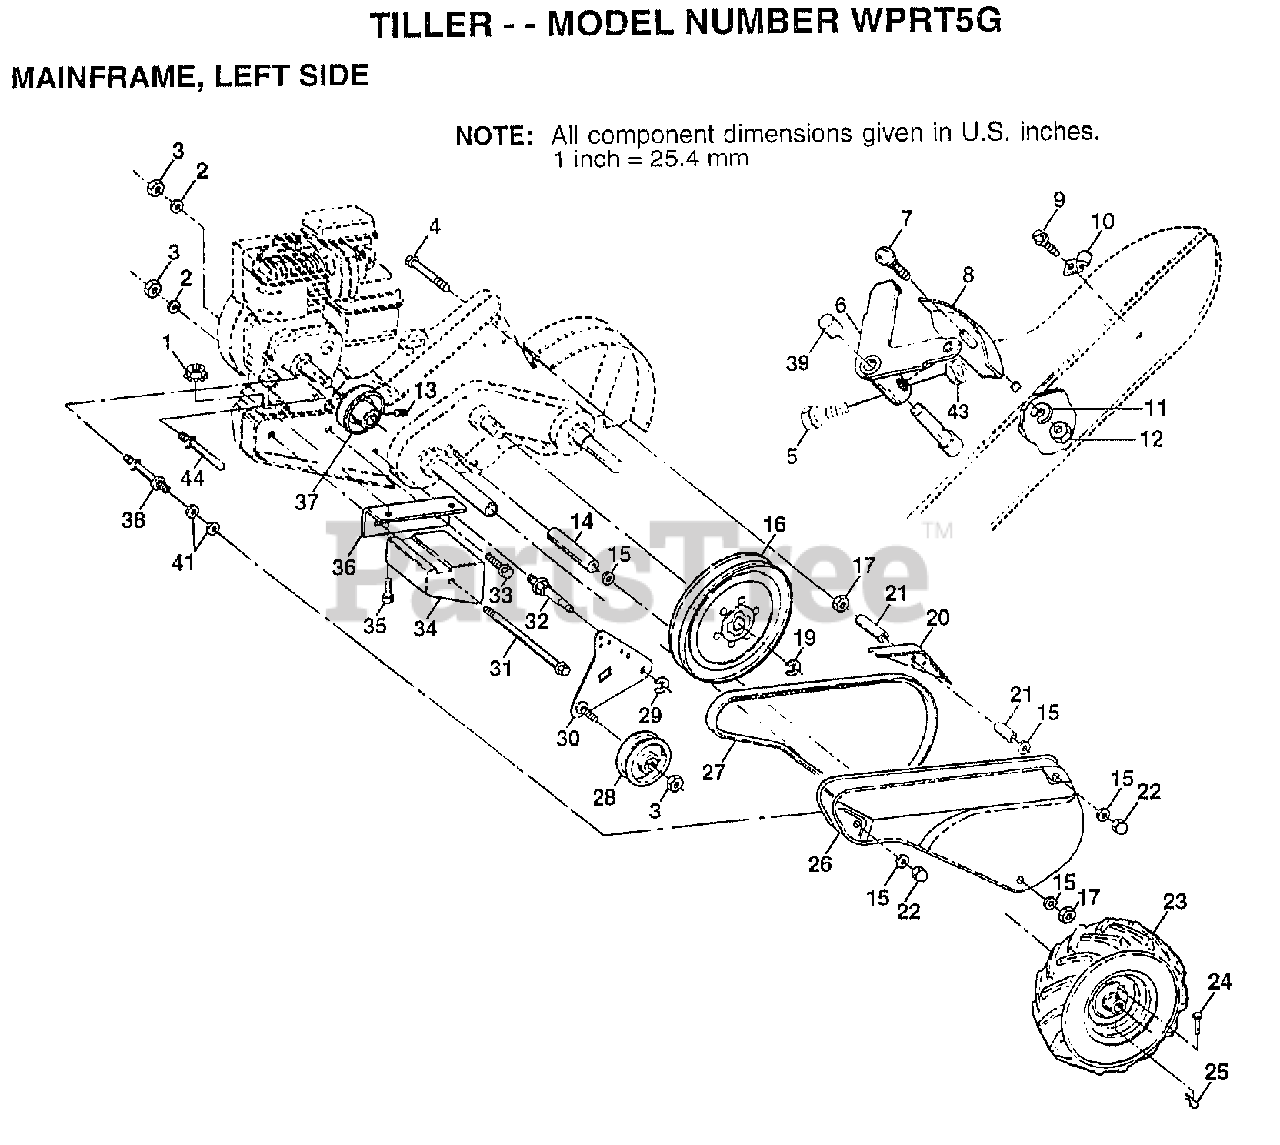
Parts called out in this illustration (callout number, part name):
2	LOCKWASHER
3	NUT.HEX.3/8-16UNC
4	BOLT TI
5	"SCREW-LEVER,SHI"
6	LEVER ASM CRT
7	BOLT
8	PANEL TI
10	CONDIUT CLIP T
11	LOCKWASHER
13	SET SCREW
14	SPACER
15	WASHER
16	SHEAVE.TRANS.
17	NUT.HEX.5/16-18
20	GUARD CRT
21	SPACER.SPLIT
22	NUT TI
23	TIRE TI
24	RIVET.DRILL.1.75
27	BELT-V
28	PULLEY-IDLER TI
29	KLIP RING
30	BRACKET ASM IDLER
31	BOLT CRT
32	SHIFT ARM CRT
33	BOLT
34	COUNTERWEIGHT CRT
35	BOLT
36	BRACKET LH CRT
37	ENGINE PULLEY
38	STUD.GUARD.BELT
39	CAP PLUNGER BLACK
41	WASHER
43	LOCKNUT
44	KEEPER.BELT.ENGINE
